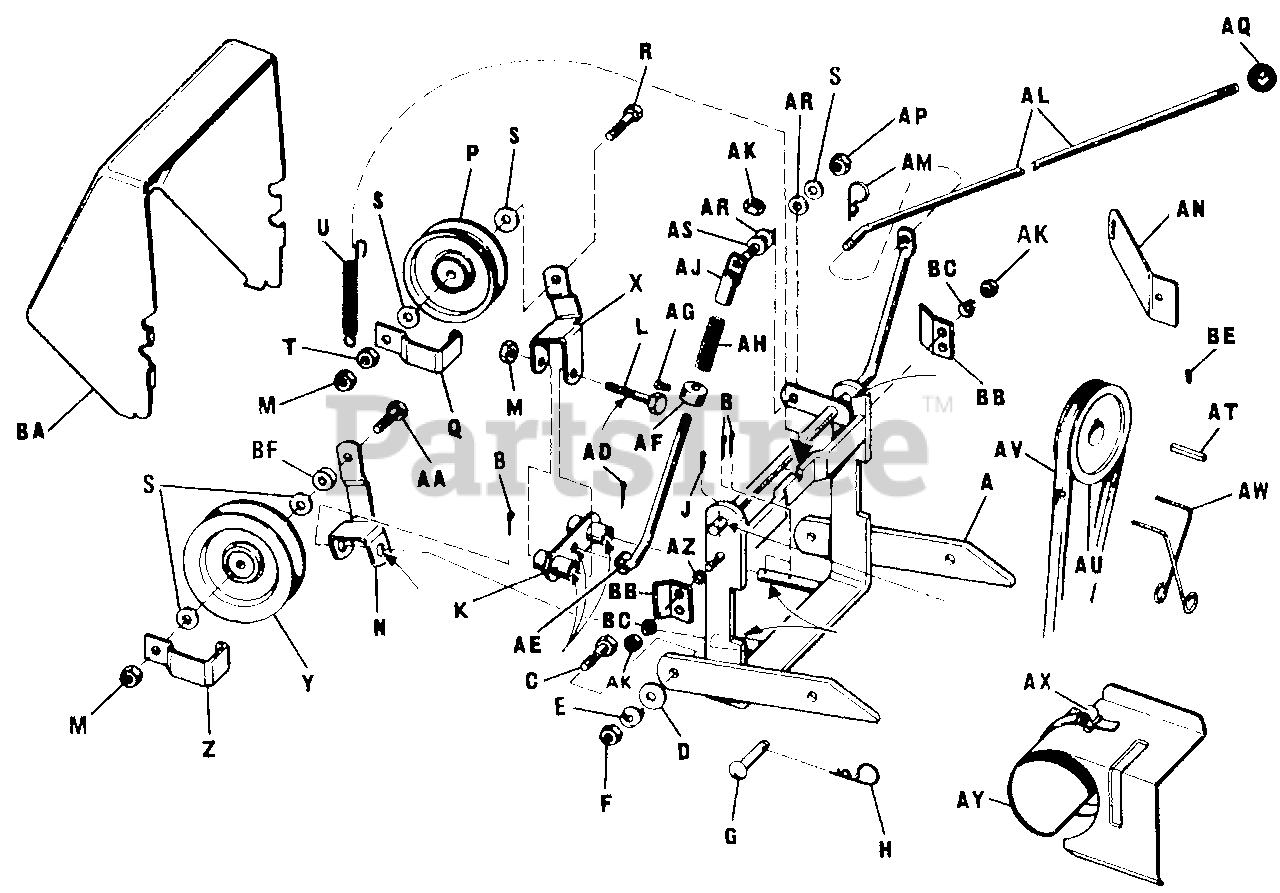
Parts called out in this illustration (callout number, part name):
A	Hitch Assembly
B	Cotter Pin, 1/8" Dia. x 1"
C	Hex. Cap Screw
D	Plain Washer, 3/8"
E	Spring Washer, 3/8"
F	Full Lock Hex Nut, 3/8"-24
G	Pin
H	Spring Clip
J	Cotter Pin, 1/8" Dia. x 1
K	Lever Ass'y Idler
L	Hex. Cap Screw
M	Full Lock Hex. Nut, 3/8"-16
N	Idler Bracket
P	Idler Pulley
Q	Guide Belt
R	Hex. Cap Screw, 3/8"-16 x 1-1/2"
S	Plain Washer, 5/16"
T	Hex. Jam Nut
U	Return Spring
X	Idler Bracket
Y	Idler Pulley
Z	Belt Guide
AA	Hex. Cap Screw, 3/8"-16 x 1-1/4"
AD	Cotter Pin, 3/32" Dia. x 3/4"
AE	Clutch Rod
AG	Set Sq. Hd. Cup Pt. Screw, 1/4"-20 x 3/8" lg.
AJ	Road Assembly Guide
AK	Hex. Full Lock Nut, 5/16"-18
AL	Clutch Handle
AM	Spring Clip
AP	Nut, Stop, 5/16"-18
AR	Nylon Washer
AU	Engine Pulley
AX	Deflector Clamp
AY	Heat Deflector
BA	Cover, Pulley
BB	Clip, Pulley Cover
BC	Spring, Concial
BE	Set Screw
